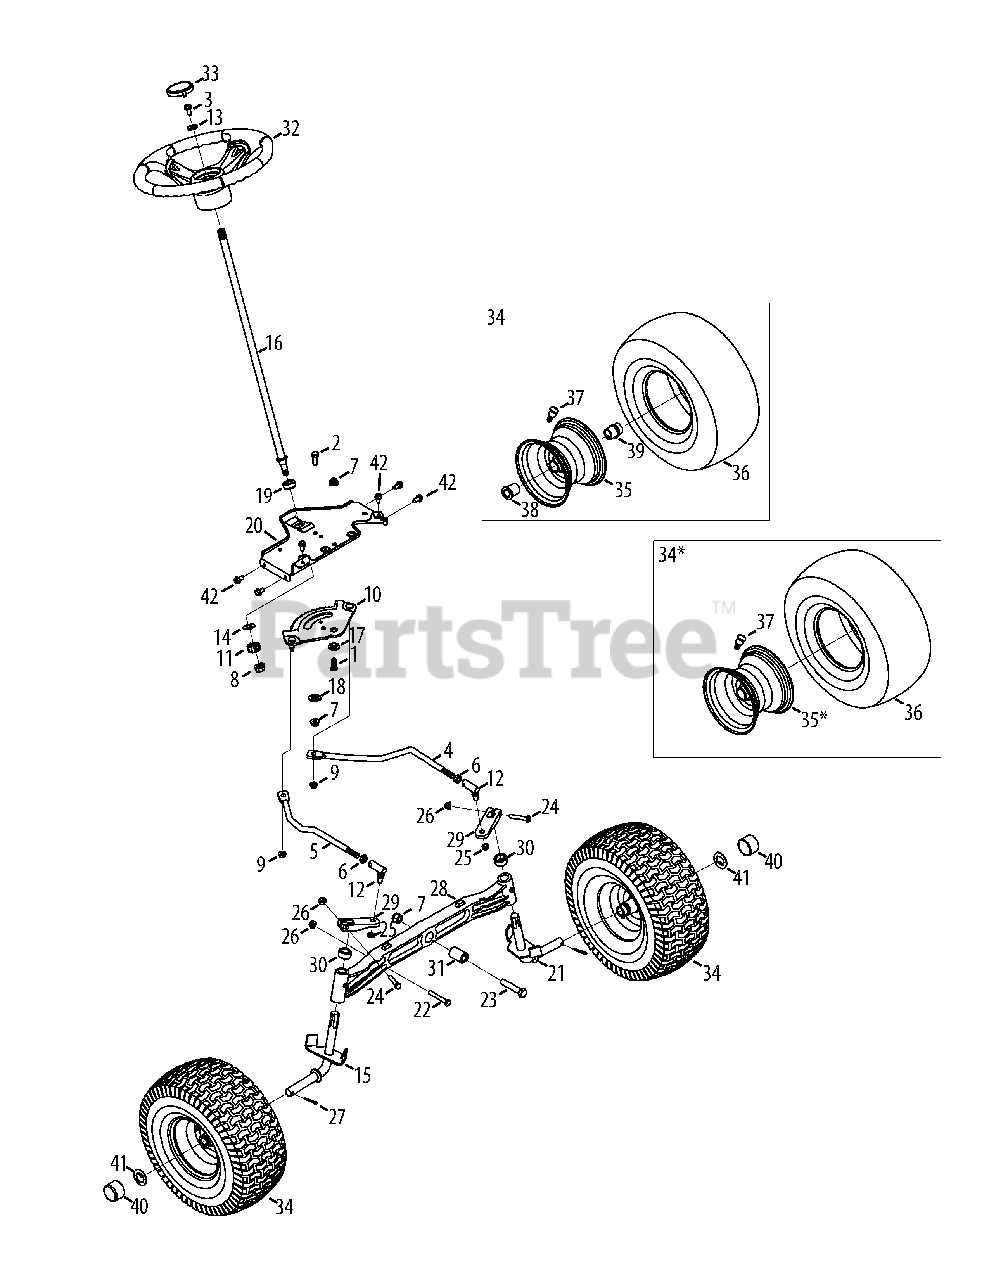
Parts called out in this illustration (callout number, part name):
1	Hex Head Screw, 3/8-16x1.00
2	Hex Head Screw, 3/8-16x1.00
3	Hex Head Screw, 5/16-18x1.00
4	LH Drag Link
5	RH Drag Link
6	Jam Nut, 7/16-20
7	Flangelock Nut, 3/8-16
8	Flangelock Nut, 7/16-20
9	Flangelock Nut, 5/16-18
10	Steering Gear
11	Steering Pinion Gear
12	Ball Joint, 7/16-20
13	Flat Washer, .406 x .875 x .105
14	Flat Washer, .51 x 1.12 x .06
15	RH Axle Assembly
16	Steering Shaft, .625 OD x 24.25 LG
17	Shoulder Spacer, .385 x 1.25 x .3025
18	Spacer, .38 x 1.375
19	Hex Flange Bearing 5/8 PM
22	Hex Head Screw, 5/16-18x2.25
23	Hex Head Screw, 3/8-16x2.50
24	Hex Head Screw, 5/16-18x1.75
25	Hexlock Nut, 3/8-24
26	Flangelock Nut, 5/16-18
27	Cotter Pin, 5/32x1.25
28	Pivot Bar Axle
29	Steering Block
30	Spacer, .71 ID x .125 OD x .56LG
31	Spacer, .385 x 1.00 x 1.5075
32	Steering Wheel, Standard Grip
33	Steering Wheel Cap, Sprig
34	Wheel Assembly
35	Rim Assembly
37	Tubeless Air Valve
38	Flange Bearing, .760 x 1.00 x 1.20LG
39	Flange Bearing, .760ID
40	Bumper Cap
41	Flat Washer, .781ID x 1.590OD
42	Screw, Self-tapping, 5/16-18, .750,
